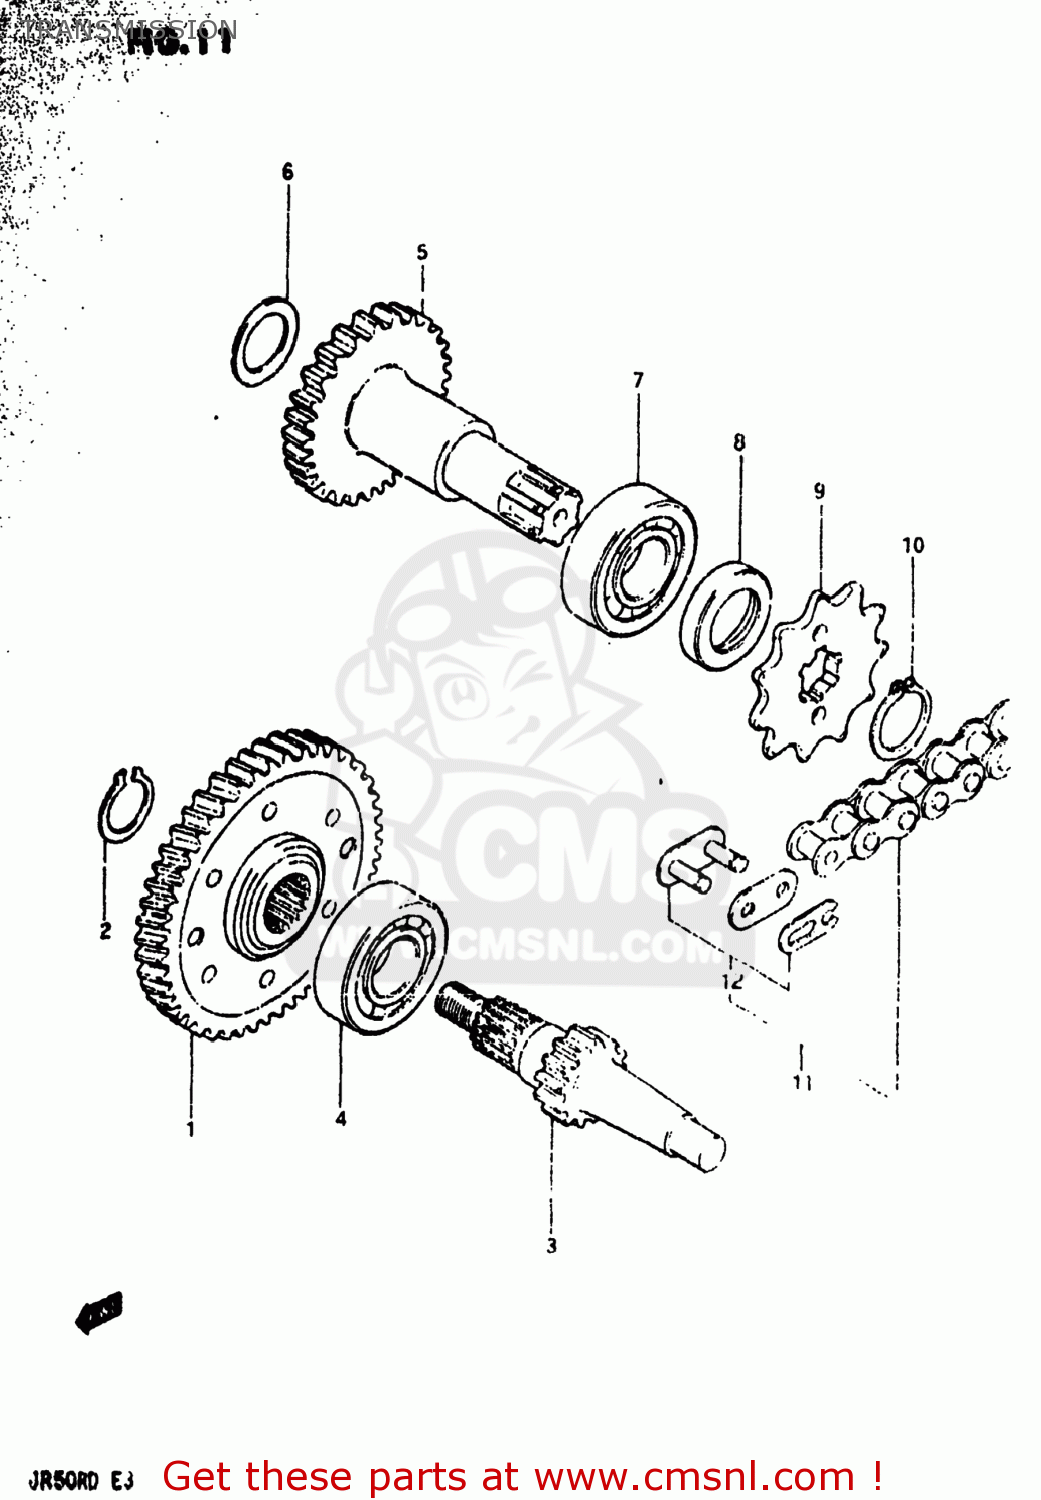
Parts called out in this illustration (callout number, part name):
1	GEAR ASSEMBLY,PRIMARY DRIVE
2	CIRCLIP
3	SHAFT,COUNTER
4	BEARING
5	SHAFT,DRIVE
6	WASHER,THRUST
7	BEARING
8	SEAL,OIL(17X29X7)
9	SPROCKET,ENGINE(NT:14)
10	CIRCLIP,16MM
11	CHAIN ASSEMBLY,DRIVE
12	JOINT ASSEMBLY,CHAIN
